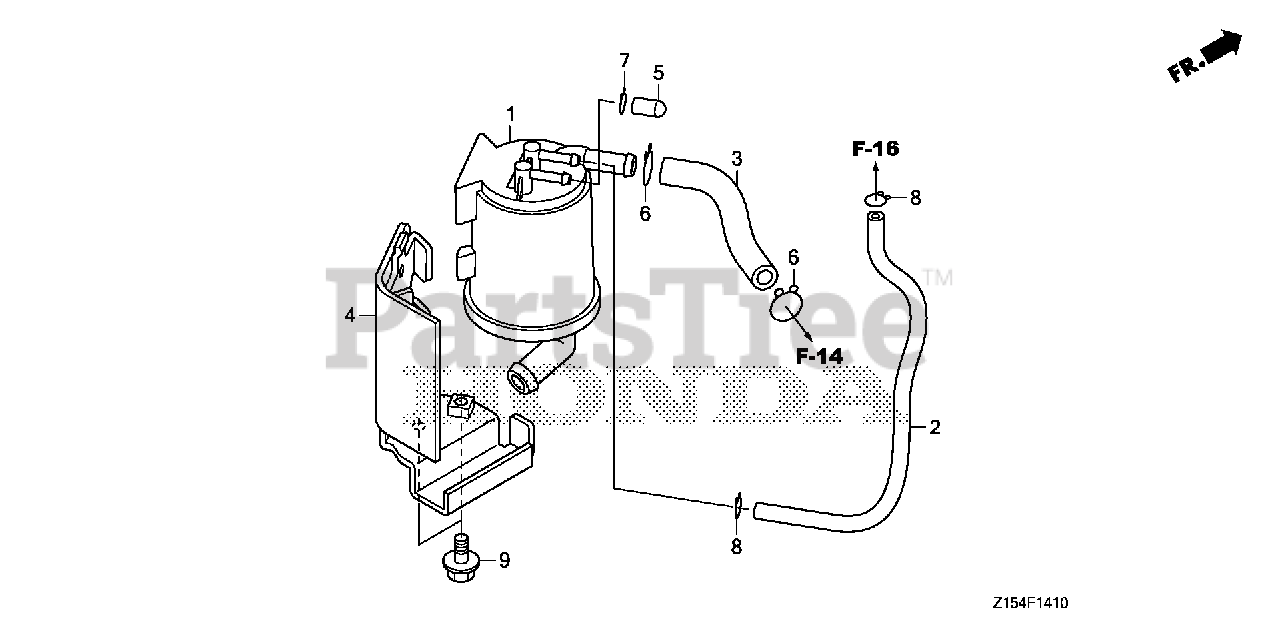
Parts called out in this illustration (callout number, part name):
1	CANISTER ASSY.
2	TUBE, CANISTER CHARGE
3	TUBE, CANISTER PURGE
4	BRACKET, CANISTER
5	CAP, SEALING
6	CLIP, TUBE
7	CLIP, TUBE (B7)
8	CLIP, TUBE (B8)
9	BOLT, FLANGE (6X12)
